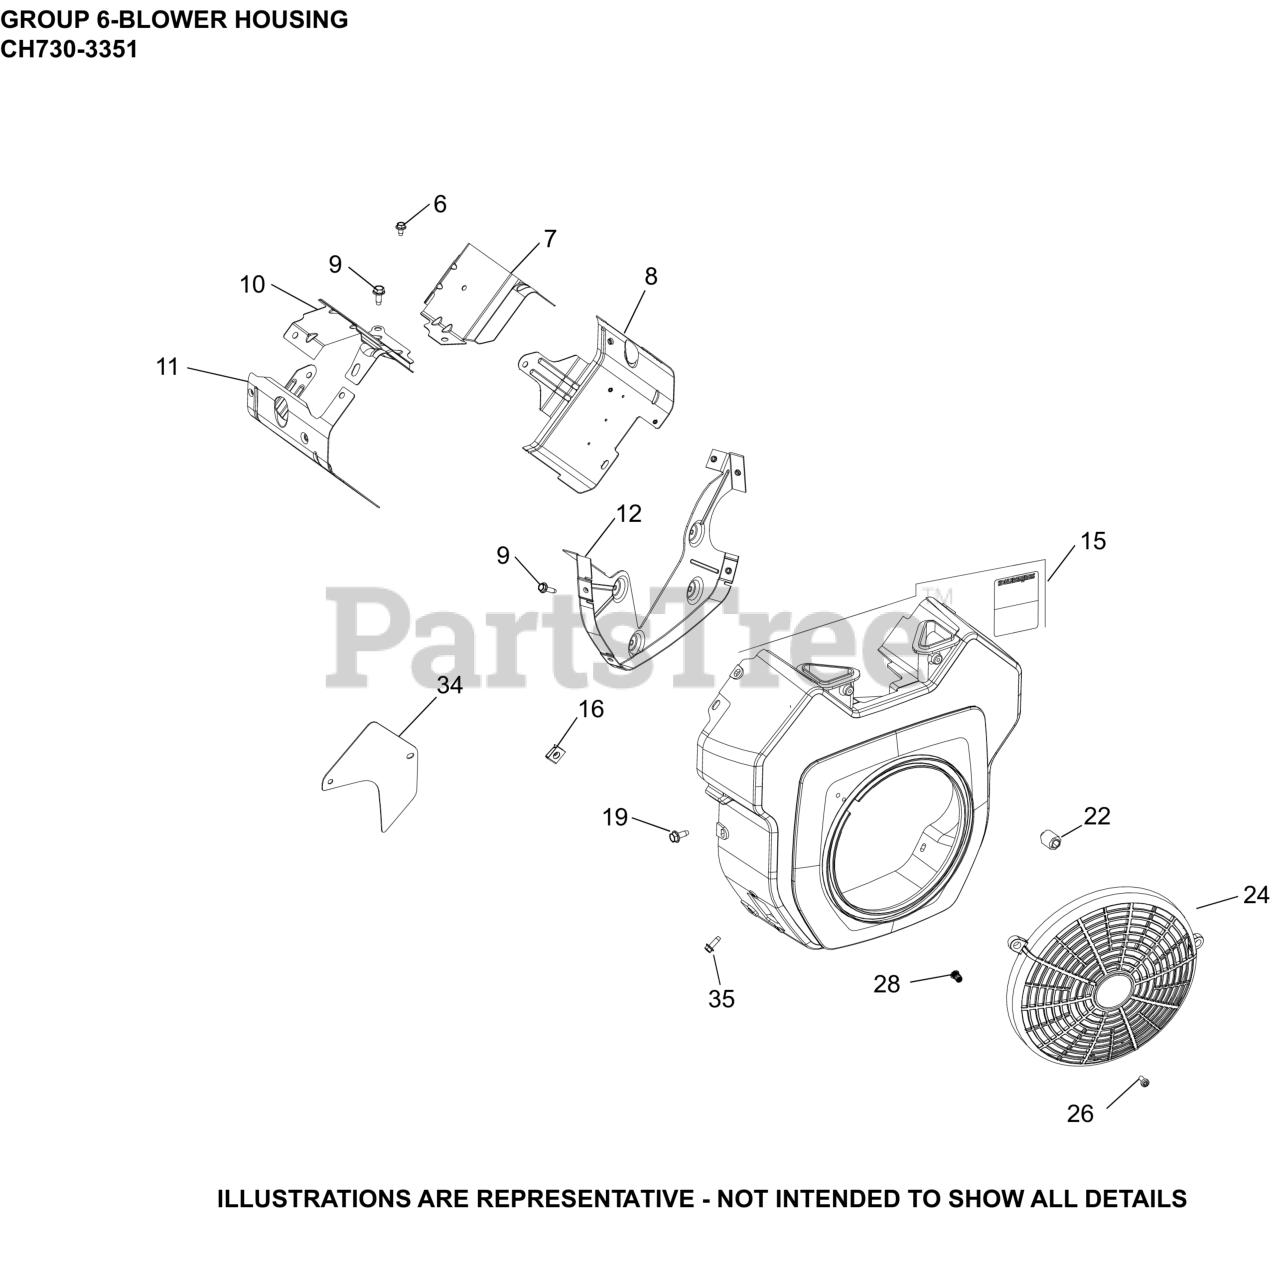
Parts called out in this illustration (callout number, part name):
6	SCREW, THREAD FORMING
7	BAFFLE, VALLEY #1 CYLINDER
8	KIT, CYL BAFFEL #1 SIDE
9	SCREW, THREAD FORMING
10	BAFFLE, VALLEY #2 CYLINDER
11	BAFFLE, LEFT BARREL
12	KIT, BACKING PLATE
15	HOUSING, BLOWER
15	KIT, BLOWER HOUSING
16	CLIP, BAFFLE MOUNTING
19	SCREW, THREAD FORMING
22	SCREW, THREAD FORMING
24	KIT, FIXED GUARD
26	SCREW, SEMS
28	INSERT, THREADED (M5)
34	KIT, ACCESS PANEL
35	SCREW, THREAD FORMING
